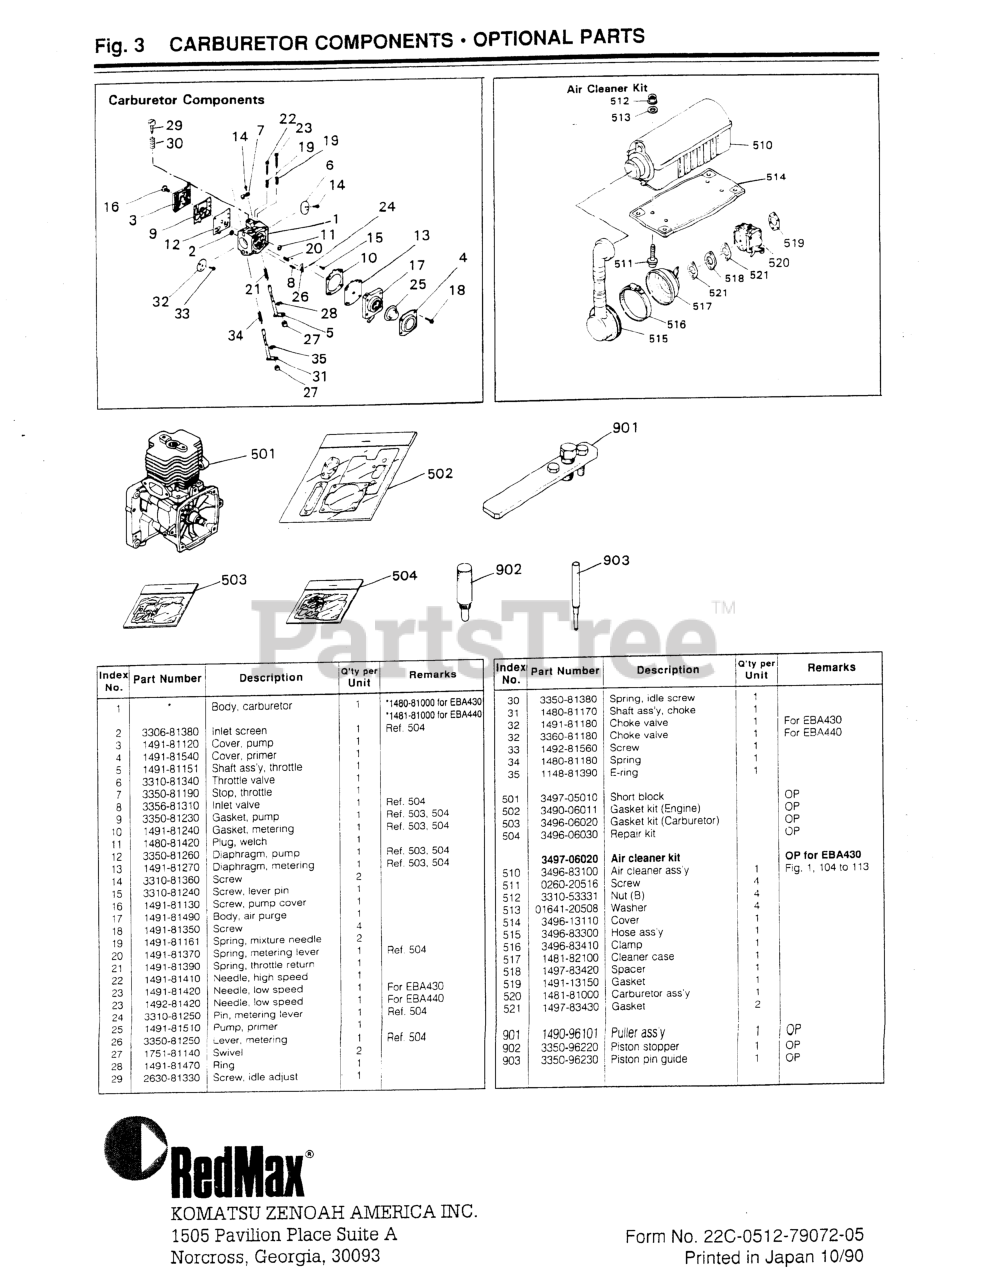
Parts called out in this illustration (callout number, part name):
3	COVER, PUMP
4	COVER, PUMP
5	SHAFT ASSEMBLY
7	THROTTLE STOP
8	VALVE, INLET
9	KIT ONLY
10	KIT ONLY
11	PLUG, WELSH
12	KIT ONLY
18	SCREW (USE 1480-81520)
20	KIT ONLY
21	SPRING
23	NEEDLE, IDLE
24	PIN, METERING LEVER
25	PUMP, PRIMER
26	KIT ONLY
30	SPRING, IDLE
31	SHAFT, CHOKE
32	VALVE, CHOKE
501	BLOCK, SHORT (NLA)
502	GASKET KIT (RPLS -06010)
503	EB430/40 DIA/GASK KIT
504	REBUILD KIT, EB430/440
510	CLEANER, AIR
511	SCREW, M5 x 16
512	NUT (B)
513	WASHER, M5 X .8
516	CLAMP
517	CASE, CLEANER
901	PULLER ASSEMBLY (TOOL)
902	STOPPER (TOOL) (RPLS 3320-9641
903	GUIDE (TOOL)
NI	AIR CLEANER KIT
